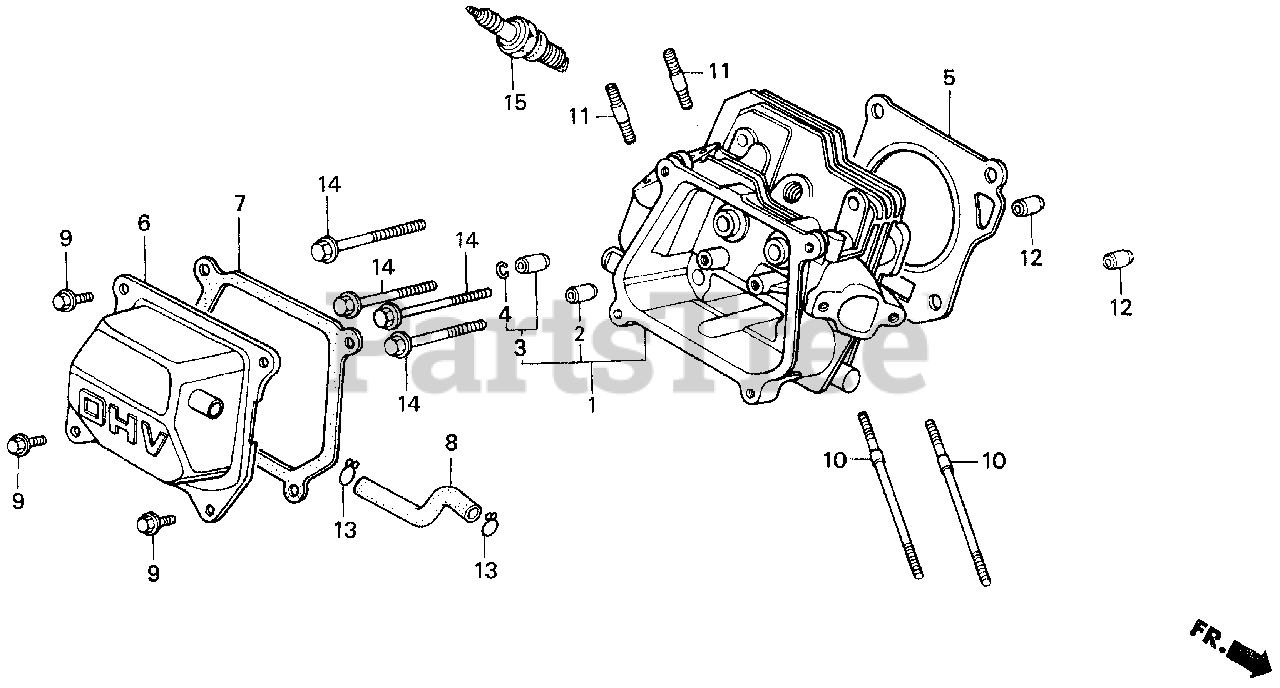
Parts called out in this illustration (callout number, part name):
1	CYLINDER HEAD
2	GUIDE, VALVE (OVER SIZE)
3	GUIDE, EX. VALVE (OVER SIZE)
4	CLIP, VALVE GUIDE
5	GASKET, CYLINDER HEAD (THAI LEAKLESS)
6	COVER, HEAD
7	GASKET, HEAD COVER
8	TUBE, BREATHER
9	BOLT, FLANGE (6X12) (CT200)
10	BOLT, STUD (6X112)
11	BOLT, STUD (8X32)
12	PIN, DOWEL (10X16)
14	BOLT, FLANGE (8X55)
15	SPARK PLUG (BPR6ES) (NGK)
15	SPARK PLUG (BPR5ES) (NGK) (NA USE ALT:98079-56876)
